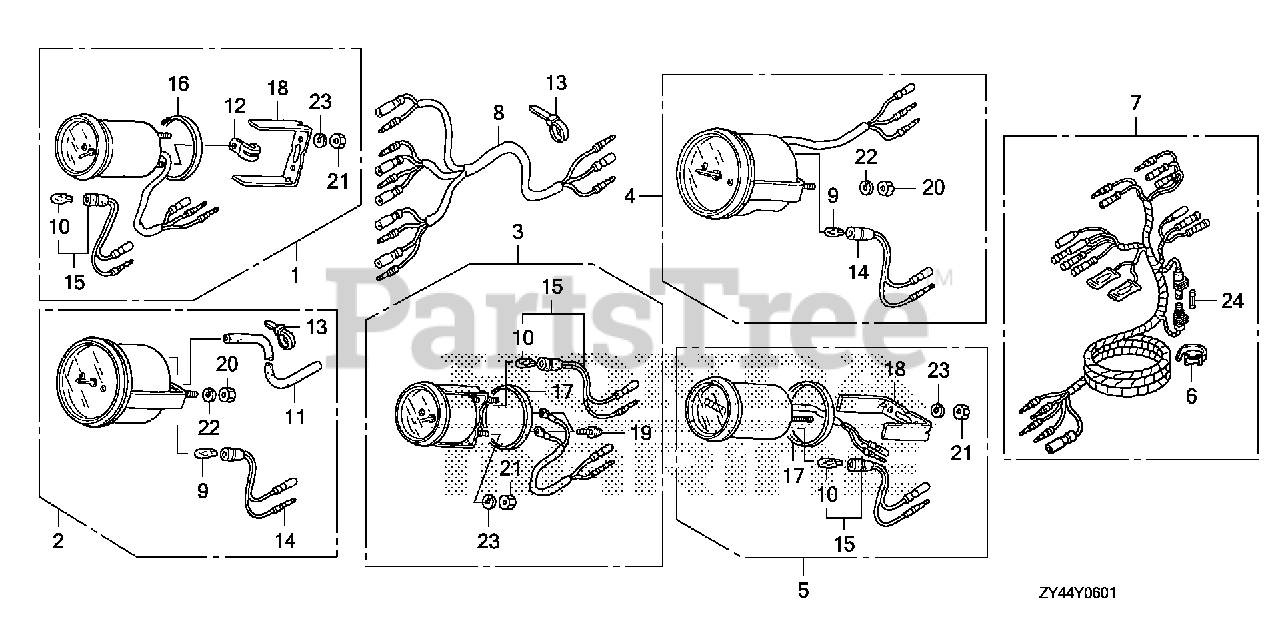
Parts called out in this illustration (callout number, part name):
1	METER KIT, TRIM
1	METER KIT, TRIM (B)
2	SPEEDOMETER KIT
2	SPEEDOMETER KIT (B)
3	METER KIT, VOLT
3	METER KIT, VOLT (B)
4	METER KIT, TACHO
4	METER KIT, TACHO (B)
5	METER KIT, HOUR (NA USE ALT:39700-ZW5-000ZA)
5	METER KIT, HOUR (B) (NA USE ALT:39700-ZW5-000ZA)
6	BAND B1, WIRE
7	HARNESS ASSY., METER (A)
8	HARNESS ASSY., METER (B)
9	BULB, WEDGE BASE (T10) (12V 1.7W) (STANLEY)
10	BULB, WEDGE BASE (12V 1.7W)
11	TUBE, SPEED METER (4X7X8000)
12	CLAMP
13	BAND, SELF-LOCK
14	SOCKET
15	SOCKET
16	GASKET
17	GASKET
18	BRACKET
19	SCREW-WASHER (3X22)
20	NUT, HEX. (5MM)
21	NUT, HEX. (4MM)
22	WASHER, SPRING (5MM)
23	WASHER, SPRING (4MM)
24	FUSE A (10A)
